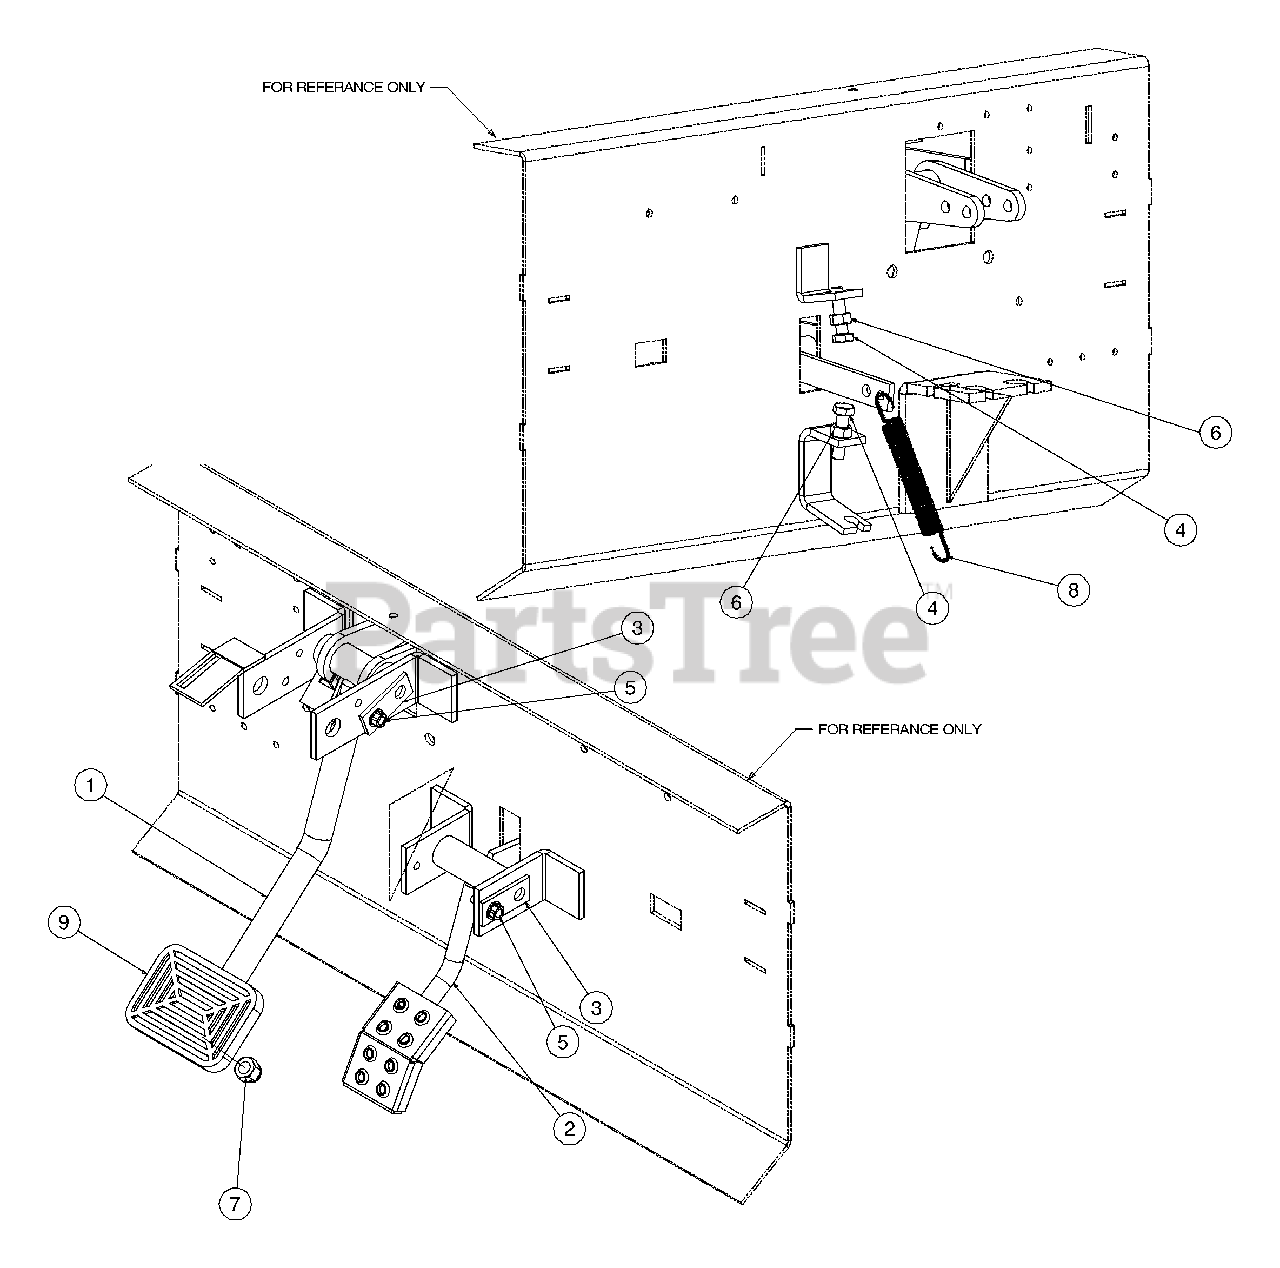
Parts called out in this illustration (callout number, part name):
3	Shaft Assembly, Pedal Pivot
4	Hex Screw, 5/16-18, 1.25, Gr5
5	Screw, Self-tapping, 1/4-20 x .75
6	Nut, Hex Lock, 5/16-18, Gr5
7	Lock Nut, Nylon, 3/8-24
8	Extension Spring .53 OD x 4.75
9	Pad, Pedal Brake
